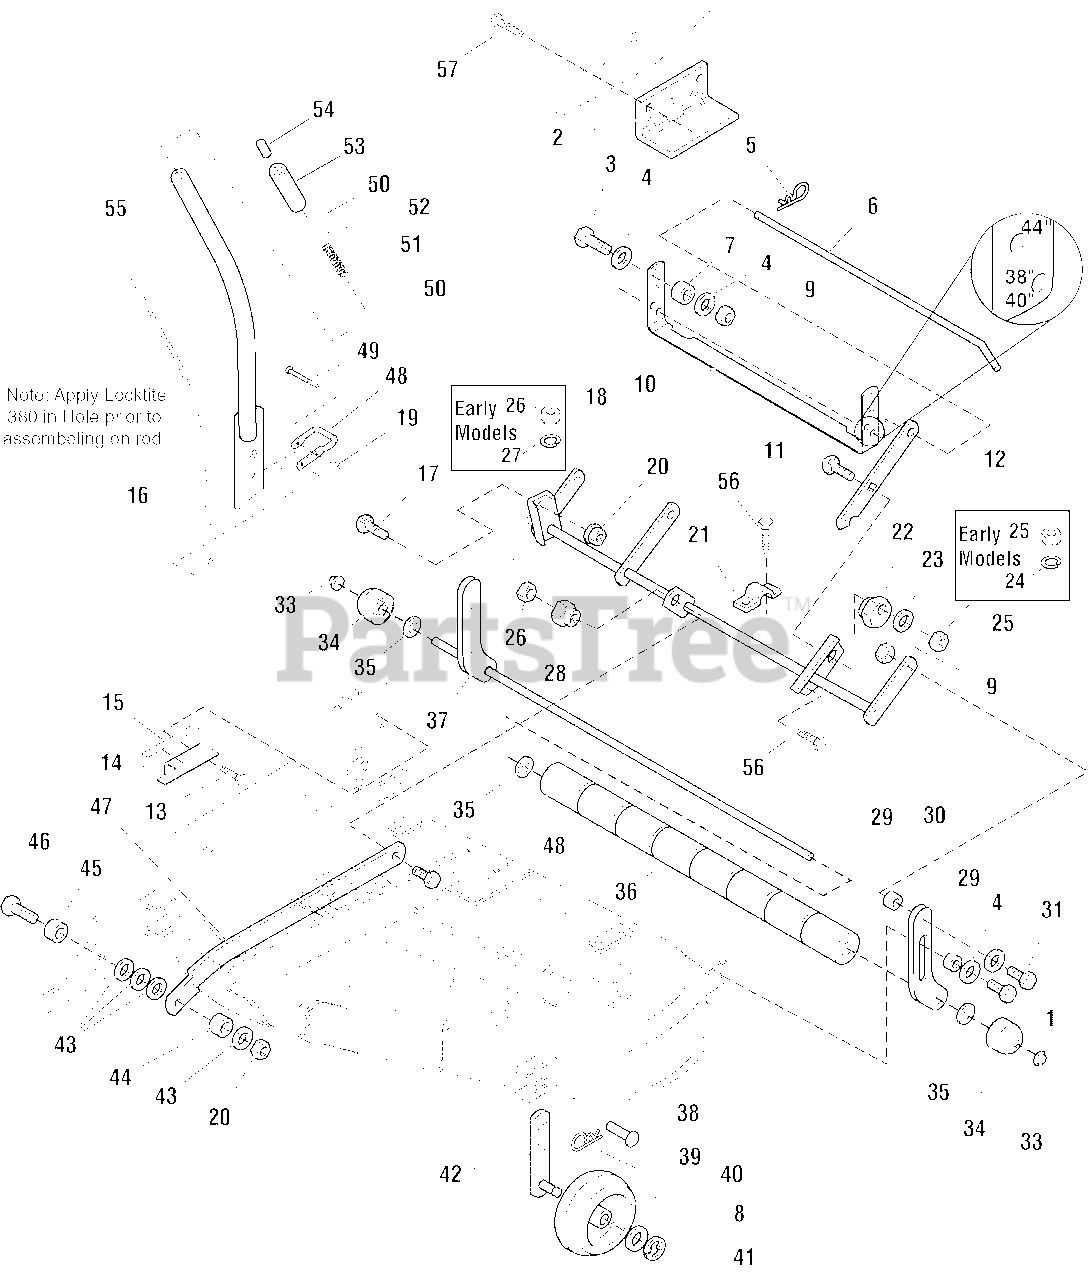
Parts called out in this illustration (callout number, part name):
1	CAPSCREW, Taptite Hex Washer Head, 5/16-18 x 1
2	BRACKET, Upstop
3	CAPSCREW, Hex Head, 5/16-18 x 1-1/4
4	WASHER, 5/16
5	CLIP, Spring
6	ROD, Transport
8	WASHER, 1/2
9	NUT, Hex Lock, 5/16-18
10	U-BRACKET
11	CARRIAGE BOLT, 5/16-18 x 1-1/4
13	CAPSCREW, Hex Head, Taptite, 5/16-18 x 1/2
14	BRACKET, Decal
15	DECAL, Height
17	CARRIAGE BOLT, 3/8-16 x 1
18	ROCKER ARM ASSEMBLY
19	NUT, Hex Lock, 1/4-20
20	NUT, Hex Adjusting, .99 DIA .687
21	STRAP
23	WASHER, Flat, 5/16
24	LOCKWASHER, 5/16 (Early Models)
25	NUT, Hex, Flange Collar Lock, 5/16-18 (Later Models)
25	NUT, Hex, Full, 5/16-18 (Early Models)
26	NUT, Hex Lock, Alum Insert 3/8-16 (Later Models)
26	NUT, Hex, 3/8-16 (Early Models)
27	LOCKWASHER, 3/8 (Early Models)
28	NUT, Hex Adjusting, .99 DIA .687
30	BAR, Roller, Support
31	CAPSCREW, Hex Head, 5/16-18 x 1
33	PUSHNUT, 5/8"
34	ROLLER, End
35	WASHER, 5/8
37	SHAFT ASSEMBLY
39	CLIP, Hair
40	GAUGE WHEEL
41	E-RING, 1/2
42	ARM ASSEMBLY, Adjustable
43	WASHER, Flat, 3/8
46	CAPSCREW, Hex Head, 3/8-16 x 2
47	ARM, Pitch
49	CAPSCREW, Hex, 1/4-20 x 2-1/4
50	WASHER
51	SPRING, Compression
52	PUSHNUT, 1/4
55	HANDLE ASSEMBLY
56	CAPSCREW, Taptie Hex Washer Head, 5/16-18 x 3/4
57	CAPSCREW, Taptite 5/16-18 x 5/8
